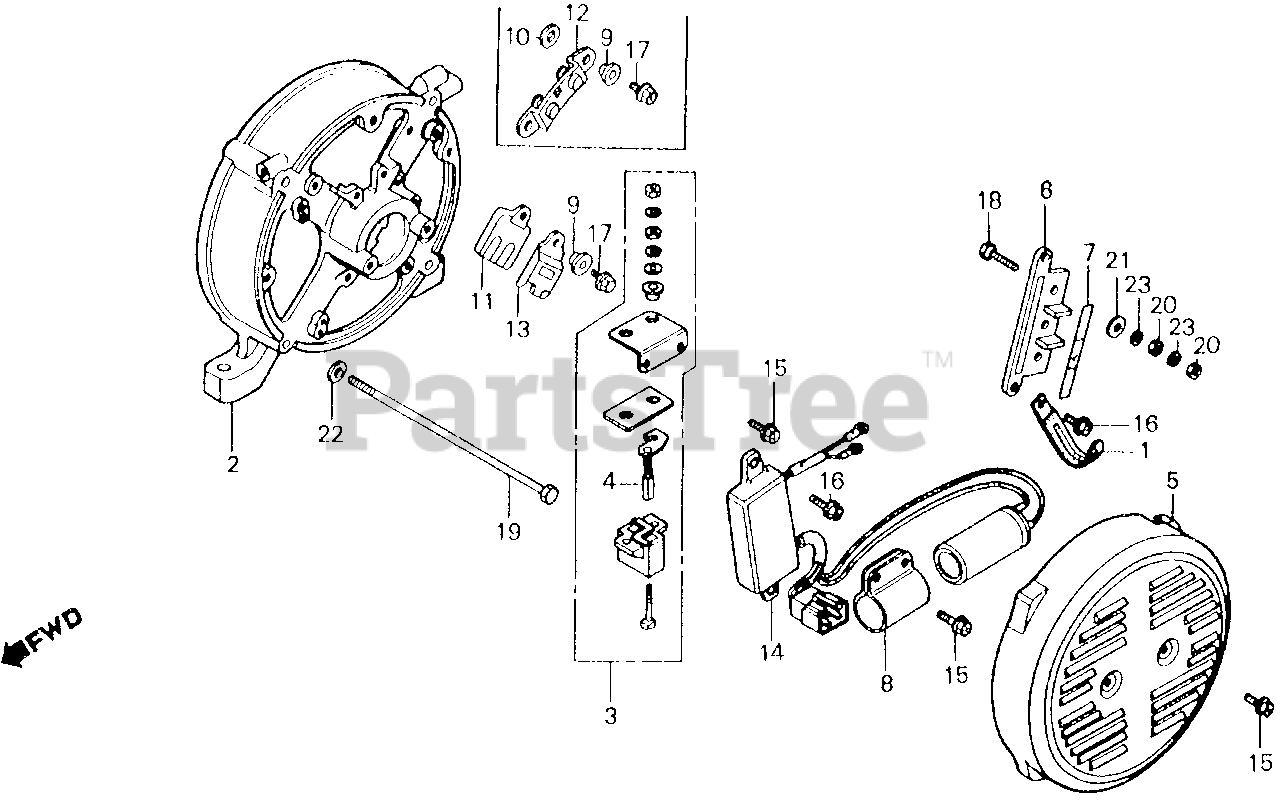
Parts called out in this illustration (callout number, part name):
1	CLAMP A, WIRE
2	HOUSING, RR. *R8* (BRIGHT RED) (NOT AVAILABLE)
3	HOLDER, BRUSH
5	COVER, ALTERNATOR END *R8* (BRIGHT RED)
6	TERMINAL, VOLT CHANGE
7	MARK, VOLT
8	HOLDER, CONDENSER
9	BUSH, INSULATING
10	WASHER, INSULATING
11	INSULATOR, DIODE
12	DIODE ASSY., D.C.
13	DIODE, D.C.
14	REGULATOR ASSY., AUTOMATIC VOLTAGE
15	SCREW, TAPPING (5X12)
16	SCREW, TAPPING (5X14)
17	SCREW, TAPPING (5X16)
18	BOLT, HEX. (5X20)
19	BOLT, HEX. (6X145) (NOT AVAILABLE)
20	NUT, HEX. (5MM)
21	WASHER, PLAIN (5MM)
22	WASHER, PLAIN (6MM)
23	WASHER, SPRING (5MM)
